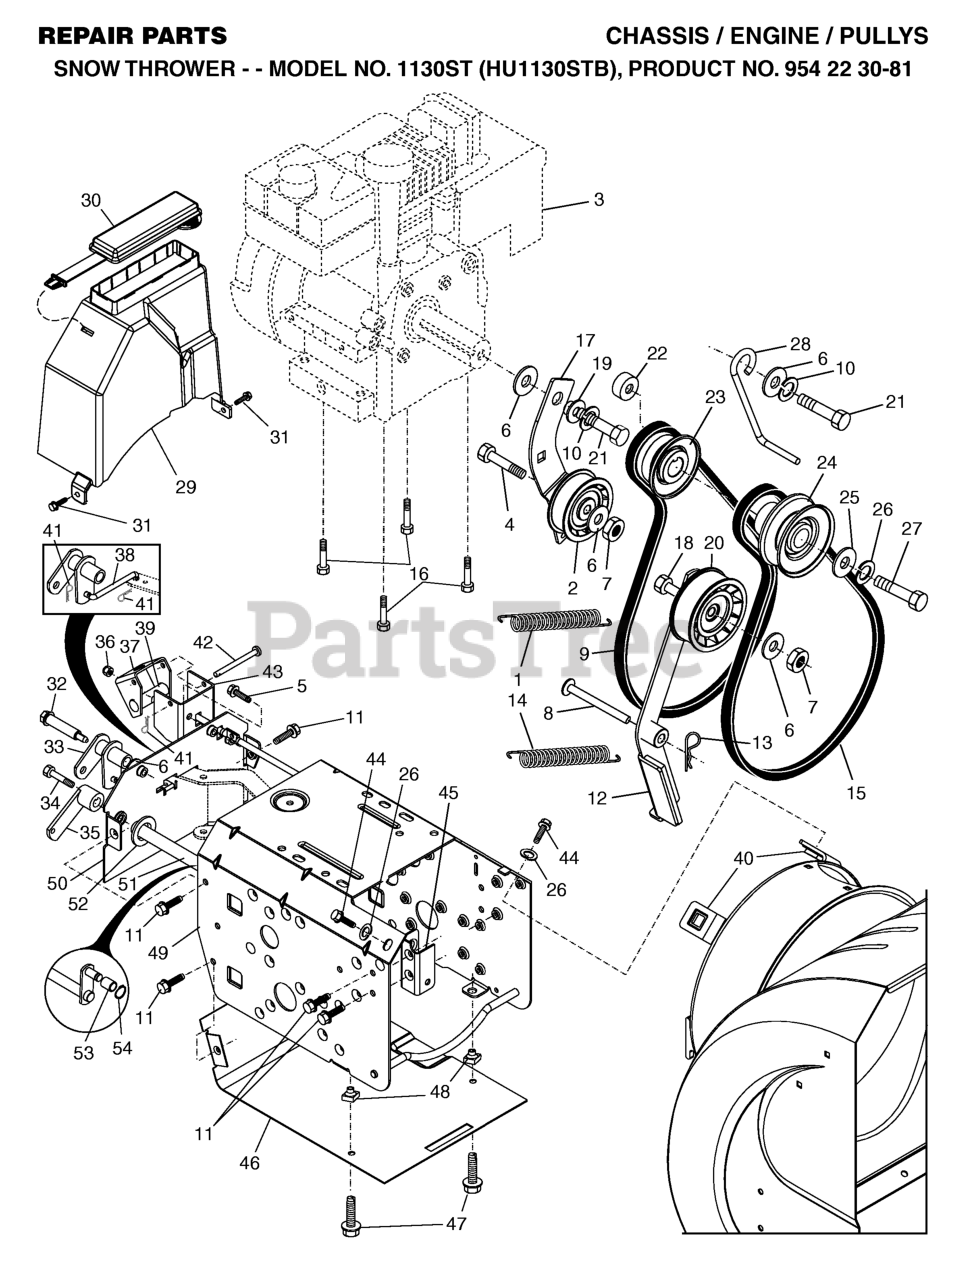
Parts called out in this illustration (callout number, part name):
1	RP SPRING, TRACTION IDLER
2	PULLEY.W/SPACER.2.25
4	BOLT.5/16-18X1-1/4 FULL.THREAD
5	SELF-TAPPING SCREW 5/16-18X3/4
6	STEEL WASHER
7	NUT.CENTERLOCK.5/16-
8	PIN, IDLER PIVOT
9	V-BELT, TRACTION DRIVE
10	WASHER.LOCK.HVY.HLCL.SPR.5/16
11	Screw 5/16-18 x 1/2 Hex, Self Tapping 5/16-18 x 1/2
12	ARM ASSEMBLY, IMPELLER IDLER
13	RETAINER CLIP PM
14	SPRING, BRAKE
15	V-BELT
16	BOLT 3/8-16X1-1/8
17	IDLER ARM
18	HEX BOLT
19	RP BUSHING, IDLER PIVOT
20	PULLEY.W/SPACER.2.75
22	SPACER, ENGINE PULLEY
23	PULLEY,ENGINE TRACTION DRIVE
24	PULLEY.ENG.IMPELLER.SNOW
26	LOCKWASHER
27	SCREW, HEX HD 3/8-24 X 1-3/8
28	GUIDE, BELT
29	BELT COVER
30	COVER.STORAGE.SNOW
31	SCREW
32	BOLT, SHOULDER 5/16-18
33	BELLCRANK SHIFTER
35	ARM, AUGER CONTROL
36	NUT.71038.31-18.HEX.NYLOCK
37	BRACKET, PIVOT
38	LINK, SPEED CONTROL
39	TRUNION, PIVOT BRACKET
40	NUT, CAGE 3/8-16
41	RETAINER CLIP
42	PIN, PIVOT BRACKET
44	BOLT
45	BRACKET, IDLER PIVOT
46	PAN, FRAME BOTTOM
47	Screw, Hex Head 5/16-18 x 3/4
48	NUT.SPEED.5/16-18
49	FRAME ASSY
50	PLATE, FRAME END
51	SHAFT, AUGER CONTROL
52	THRUST WASHER
53	ROLLER.ACTUATOR
54	RETAINING RING
